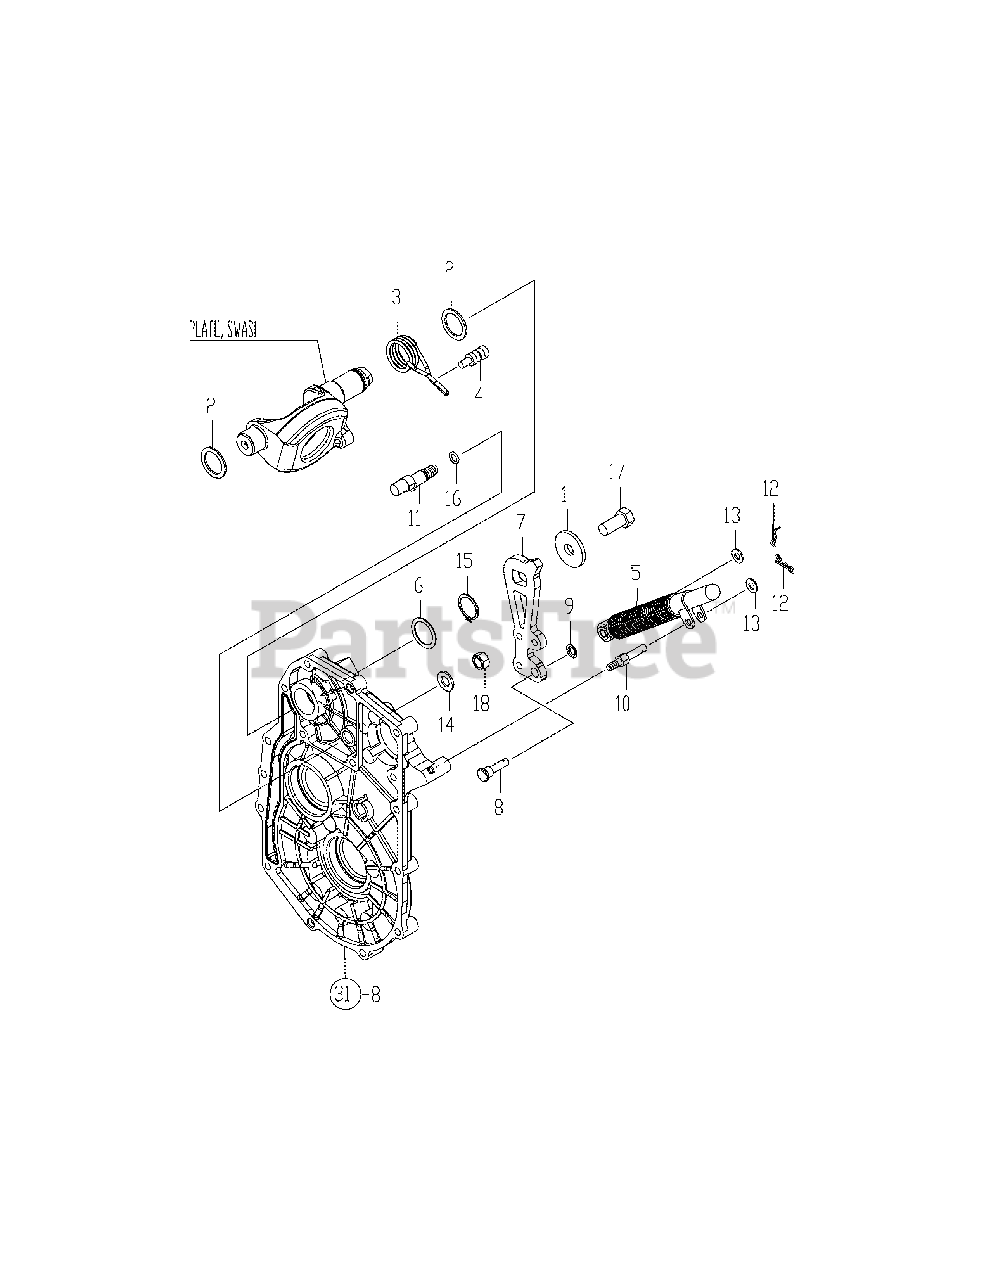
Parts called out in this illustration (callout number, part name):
1	Washer, 44X14X4.5
2	Washer, 28X38X2
3	Spring, Centering
5	Absorber, Shock
6	Washer, 29X35X1
8	Pin (Control Arm)
16	Packing, P 10A
